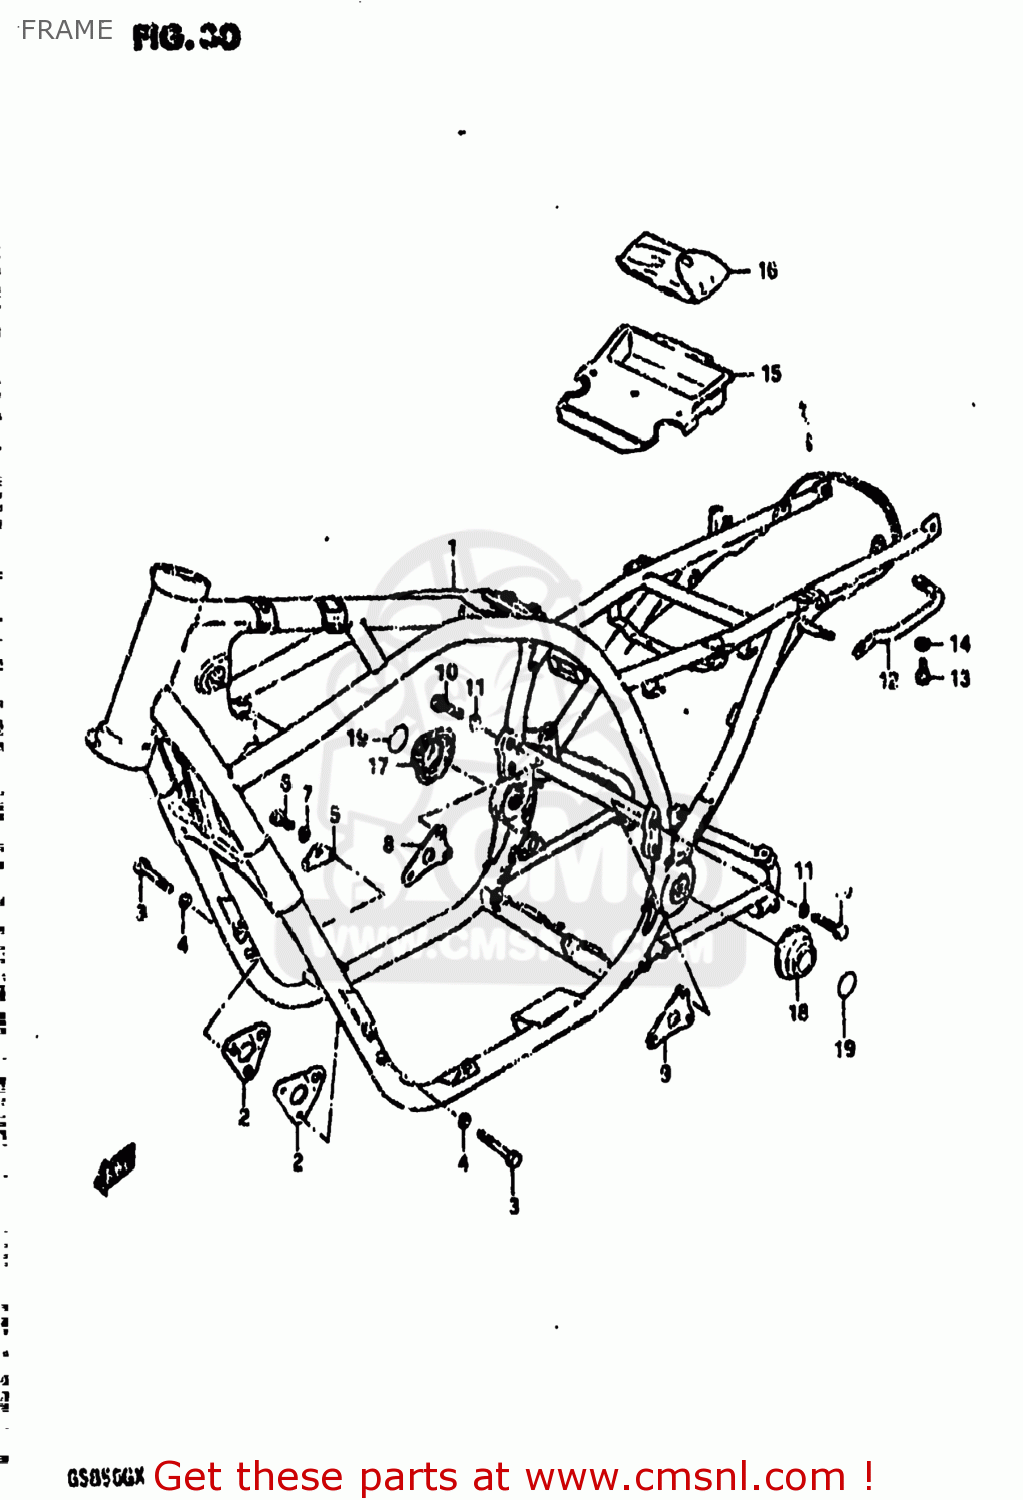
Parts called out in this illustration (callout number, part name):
1	FRAME
2	PLATE,ENGINE MOUNTING
3	BOLT
4	LOCK WASHER
5	PLATE,ENGINE MOUNTING
6	BOLT
7	LOCK WASHER
8	PLATE,ENGINE MOUNTING
9	PLATE,ENGINE MOUNTING
10	BOLT 8X40
11	LOCK WASHER
12	GRIP,FRAME
13	BOLT
14	WASHER
15	HOLDER,TOOL
16	TOOL SET
17	COVER,REAR SWING ARM PIVOT
18	COVER,REAR SWING ARM PIVOT
19	TAPE,REAR SWING ARM PIVOT
